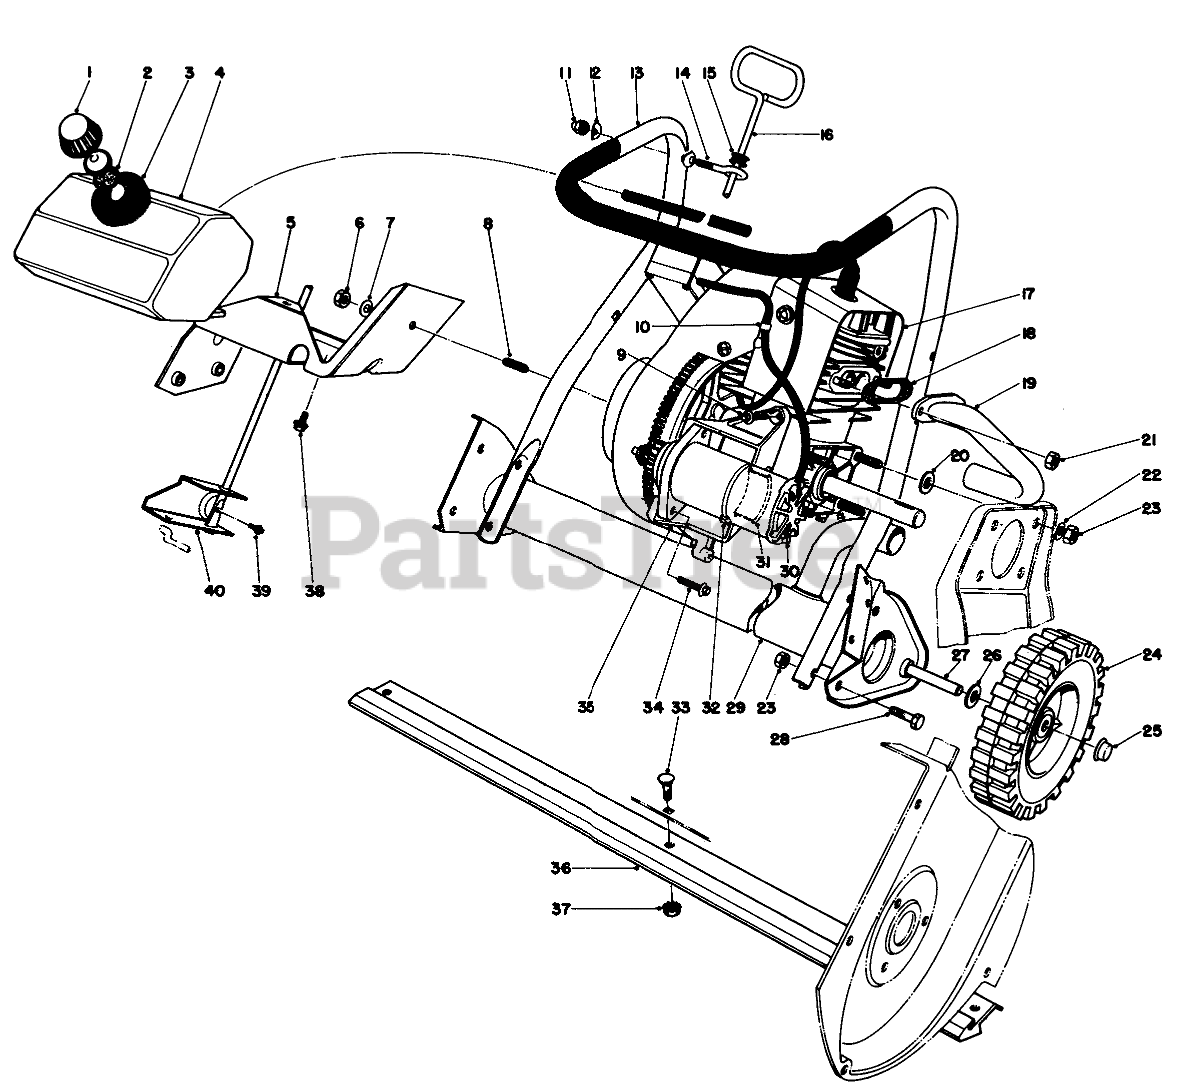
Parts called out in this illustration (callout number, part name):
1	Gas Cap (Incl. Ref. #2)
2	GAS CAP GASKET
3	FOAM PAD
4	Gas Tank
5	Rear Support Engine
6	NUT-LOCK, CONE
7	WASHER-FLAT
9	Screw
11	NUT-CAP
12	WASHER
13	Lower Handle
14	Bolt-Eye
15	GROMMET
16	Rod Vane Adjustment
17	Engine
18	EXHAUST GASKET
19	Exhaust Pipe
20	WASHER-FLAT
21	NUT-LOCK, CONE
22	WASHER-PLAIN
23	NUT-LOCK, NI
24	WHEEL
25	RETAINER-PUSH ON
26	WASHER-FLAT
28	SCREW-HH
29	EXHAUST MUFFLER ASM
30	Motor & Switch Housing
31	RR MOTOR SUPPORT
32	TIE-CABLE
33	BOLT-CARR
34	SCREW-FLOW, TAPTITE
35	Bracket-Motor Mount
36	SCRAPER
37	NUT-KEPS
38	SCREW
39	SCREW
40	Bracket-Vane Adjustment
